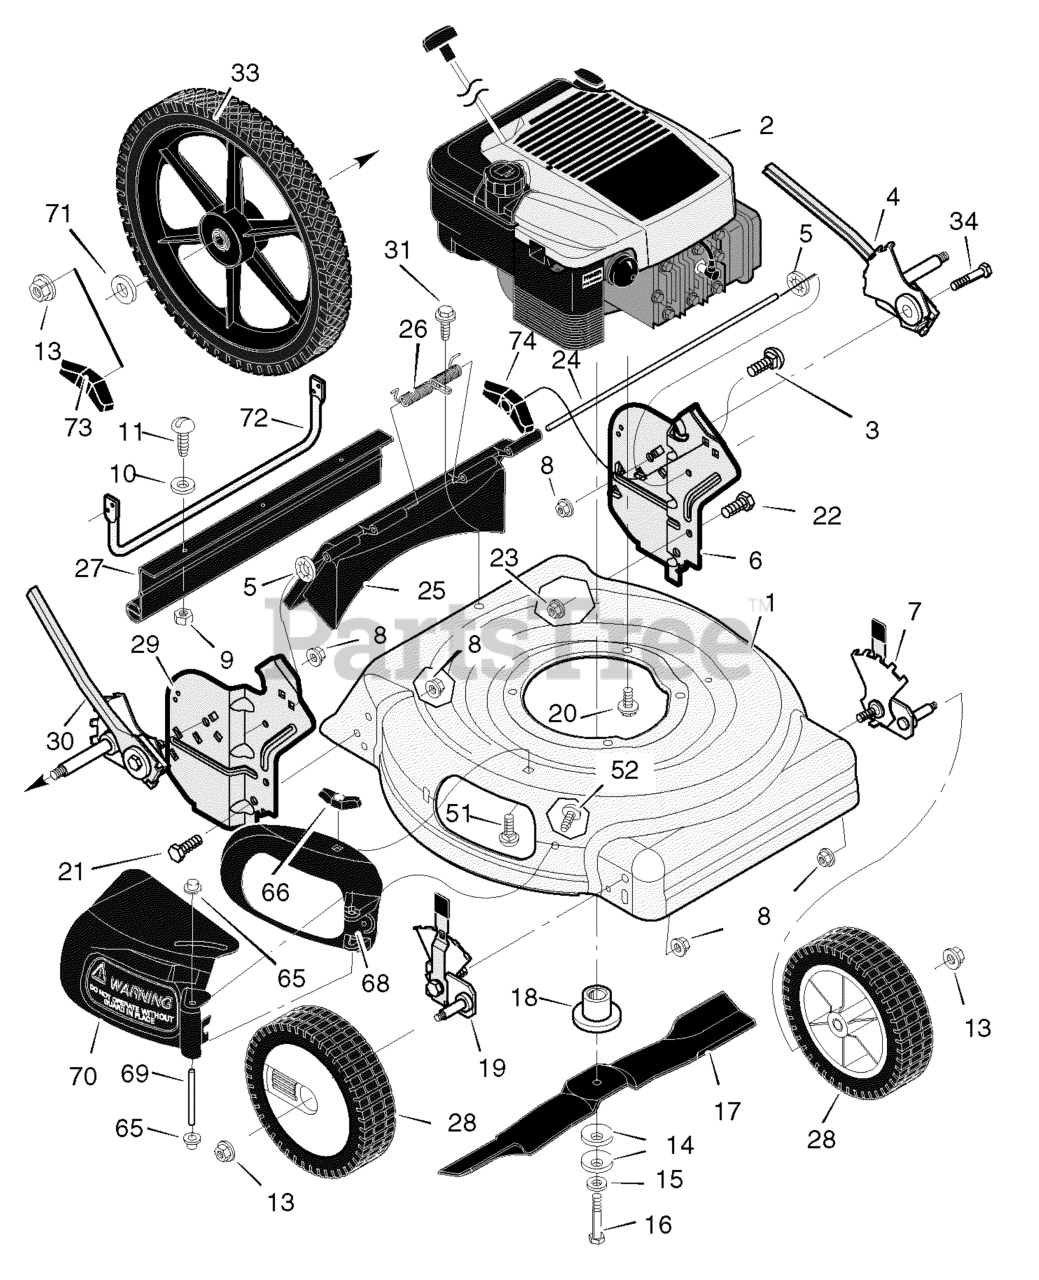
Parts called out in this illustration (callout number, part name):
1	Housing
2	Engine *
3	Bolt, Carriage
4	Adjuster, Left Rear Height
5	Retainer, Push
6	Bracket, Left Handle
7	Adjuster, Left Front Height
8	Nut, Flange
9	Nut, Hex
10	Washer
11	Screw
13	Nut, Flange
14	Washer, Belleville
15	Washer
18	Adapter, Blade
19	Adjuster, Right Front Height
20	Bolt, Engine
21	Bolt
22	Bolt
23	Nut, Flange
24	Rod, Pivot
25	Door, Rear (Black)
25	Door, Rear (Gray)
26	Spring
27	Guard, Rear
28	Wheel & Tire *
29	Bracket, Right Handle
30	Adjuster, Right Rear Height
33	Wheel, Rear *
51	Bolt, Carriage
65	Push On Cap
66	Wingnut
68	Bezel (Black)
68	Bezel (Gray)
69	Pin, Pivot
70	Deflector, Chute (Black)
70	Deflector, Chute (Gray)
